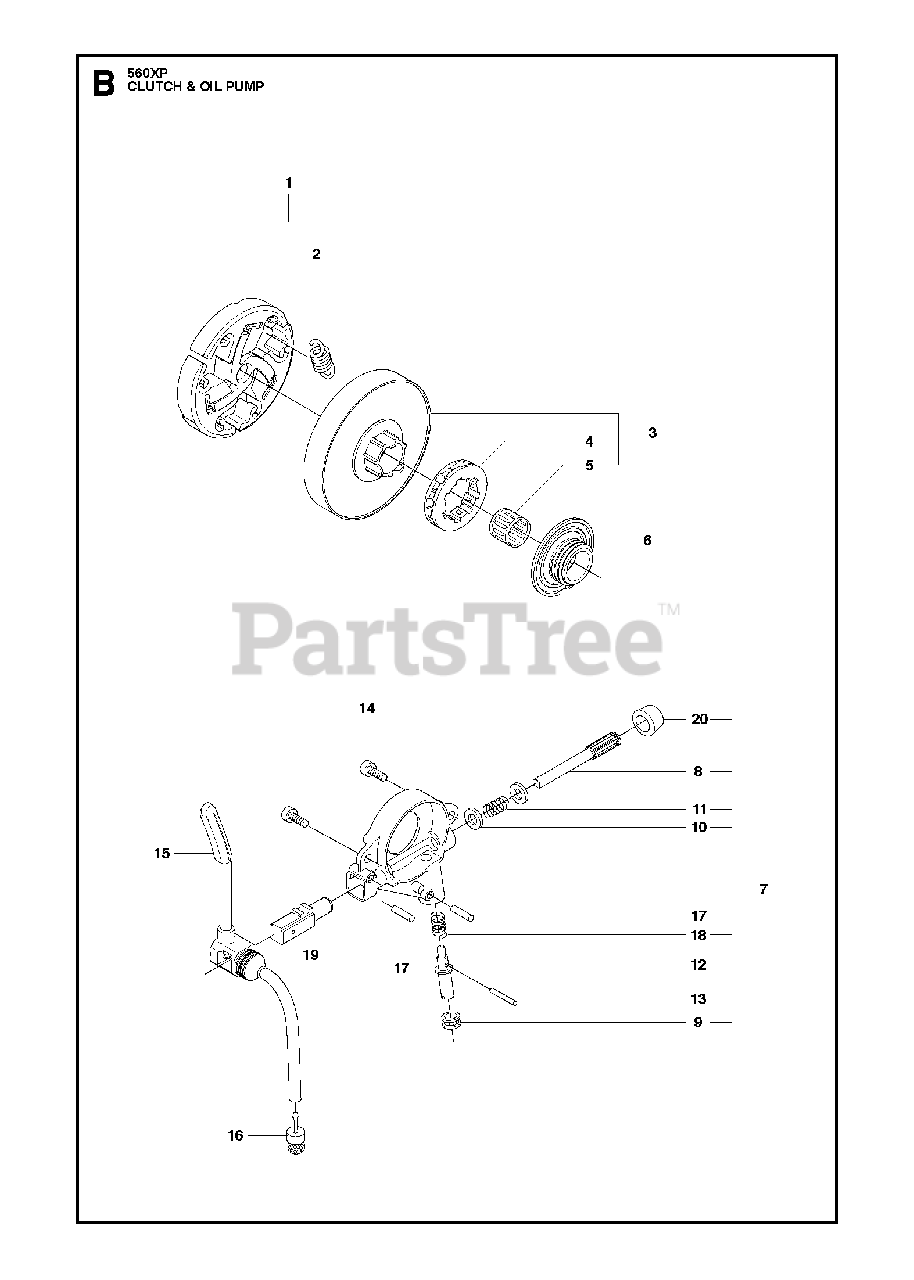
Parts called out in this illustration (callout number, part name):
1	CLUTCH ASSY
2	SPRING
3	RP CLUTCH DRUM ASSY
3	CLUTCH DRUM ASSY
4	RIM SPROCKET 7T .325
4	68210 RIMSPROCKET
5	NEEDLE BEARING
6	WORM WHEEL
7	OIL PUMP ASSY
8	PUMP PISTON
9	CASING
10	WASHER
11	SPRING
12	RP ADJUSTING SCREW
13	PIN
14	SCREW IHSCM
16	OIL PLUMMET
17	PIN 3X10
18	SPRING
19	PUMP CYLINDER
20	SEALING PLUG
